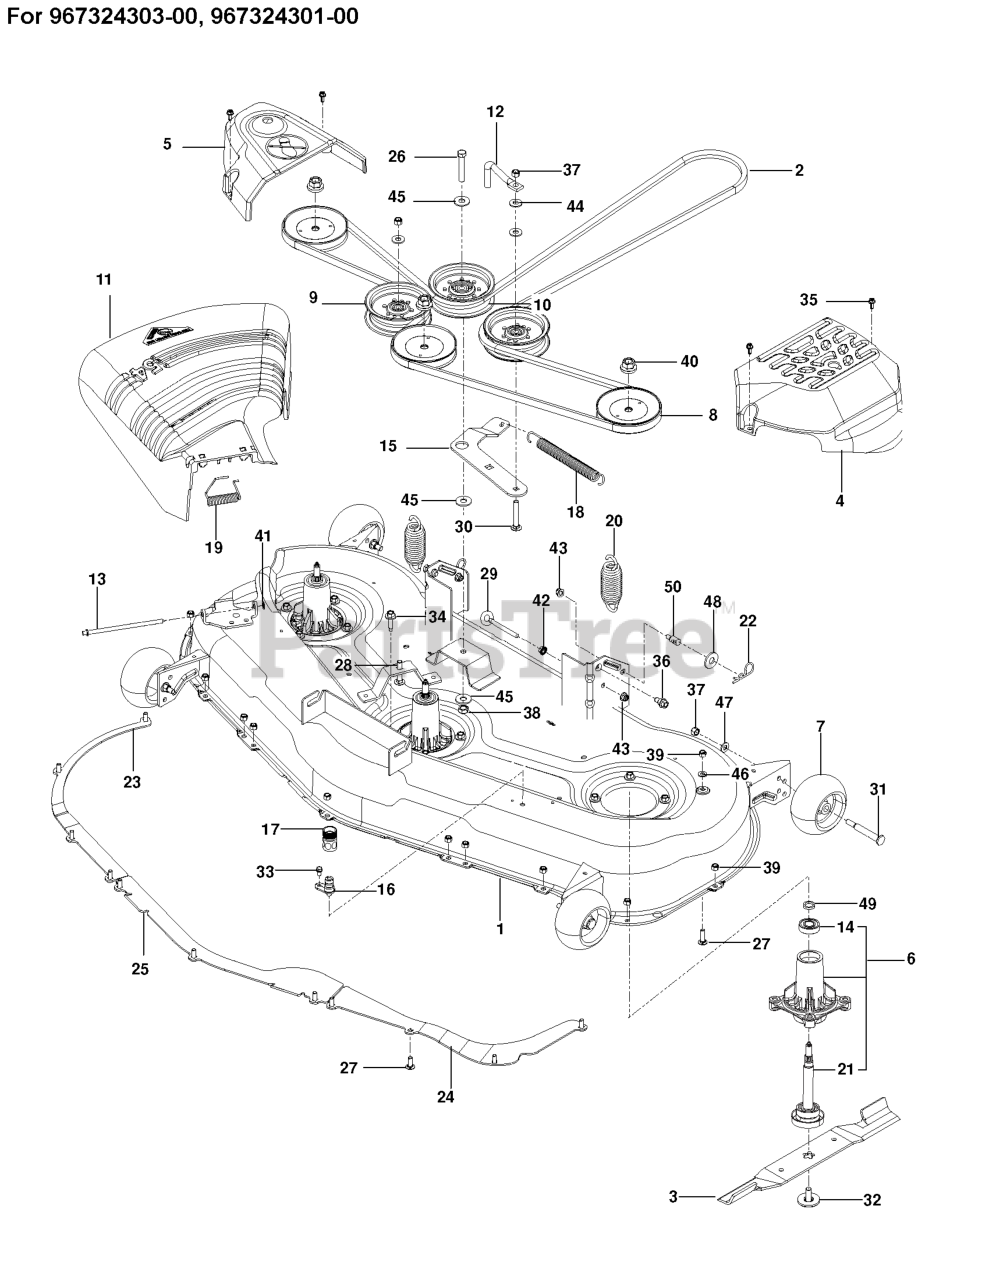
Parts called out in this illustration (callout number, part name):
1	DECK SVC W/DECALS 54" ORG
2	BELT.DECK.52".54"
3	BLADE.BAGGING.54"
4	COVER.MANDREL.LH.DECK.54"
5	COVER.MANDREL.RH.DECK.54"
6	MANDREL.W/SPCR.BRG.TALL.NONREV
7	WHEEL GAGE DONUT
8	PULLEY MANDREL
9	PULLEY.IDLER.2006
10	PULLEY.IDLER.MWR.STATI.LH
11	DEFLECTOR.BLACK.54"
12	BELT KEEPER 5"
13	ROD.HINGE
15	ARM ARM.IDLER.54". RZ BLACK MS
15	ARM.IDLER.BLACK
16	PORT.WASHOUT
17	COUPLING.QUICK CONNECT
18	SPRING, DECK BELT
19	SPRING, TORSION
21	SHAFT ASM MANDREL
22	HAIRPIN #4
23	BAFFLE.RIGHT.54"
24	BAFFLE.LEFT.54"
25	BAFFLE CENTER 54" MOWER
26	BOLT 7/16-14 X 2-1/2 GR 5 ZD
27	BOLT 5/16C X 3/4" CARRIAGE
28	RHSNB 3/8C X 2
29	EYE BOLT 5/16 X 3.50
30	CARRIAGE BOLT 3/8-16 X
31	SHOULDER BOLT 1/2X2-5/8 ZD SPE
32	BLADE BOLT ASSY-7/16" TB REPL
33	BOLT 1/4-20 X 1/2 HWST
34	WASHER HEAD SCREW
35	SCREW- 1/4-20 X 5/8
36	BOLT.SHOULDER
37	NUT 3/8-16 NYLOC
38	7/16-14 HEX NUT W/NYL RING ZD
39	NUT 5/16 NYLOC
40	LOCKNUT - 9/16
41	PUSH NUT
42	NUT 5/16C WHIZ
43	5/16-18 NYLOC FLANGE NUT
44	WASHER 3/8 FLAT
45	WASHER 7/16 FLAT ZD
46	FLAT WASHER 5/16 SAE
47	WASHER 3/8 SAE FLAT
48	WASH USS FLAT 1/2
49	WASHER.SPACER.MANDREL
50	STUD.FASTNER.W/ANTI-ROTATE
